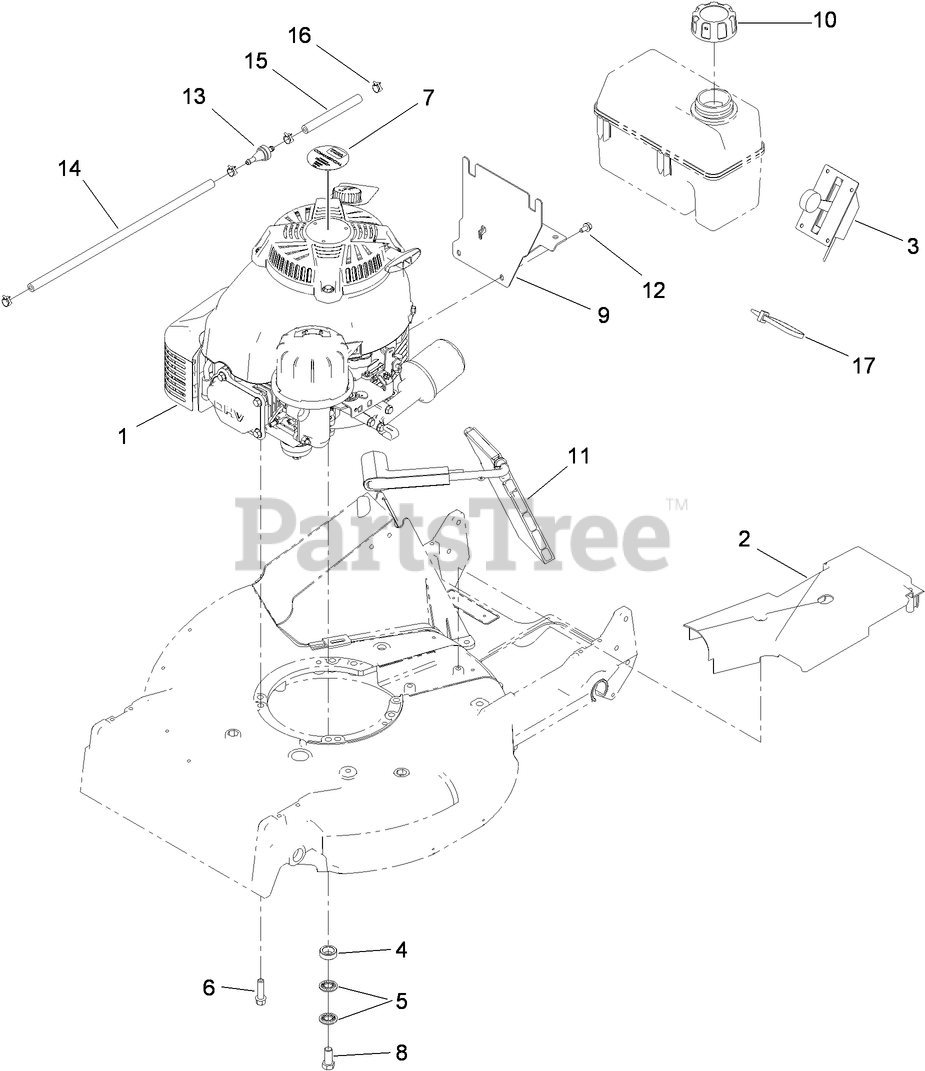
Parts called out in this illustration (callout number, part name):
1	ENGINE-KAWASAKI, FJ180V-AM07-M
2	COVER-BELT
3	CONTROL-THROTTLE
4	SPACER-SHAFT, OUTPUT
5	WASHER-SPRING
6	SCREW-TAPTITE
8	SCREW-HH
9	MOUNT-TANK
10	CAP-GAS
11	DISCHARGE DOOR ASM
12	SCREW-HWH
13	FILTER-FUEL
14	HOSE-FUEL
15	HOSE-FUEL
16	CLAMP-HOSE
17	TIE-CABLE
